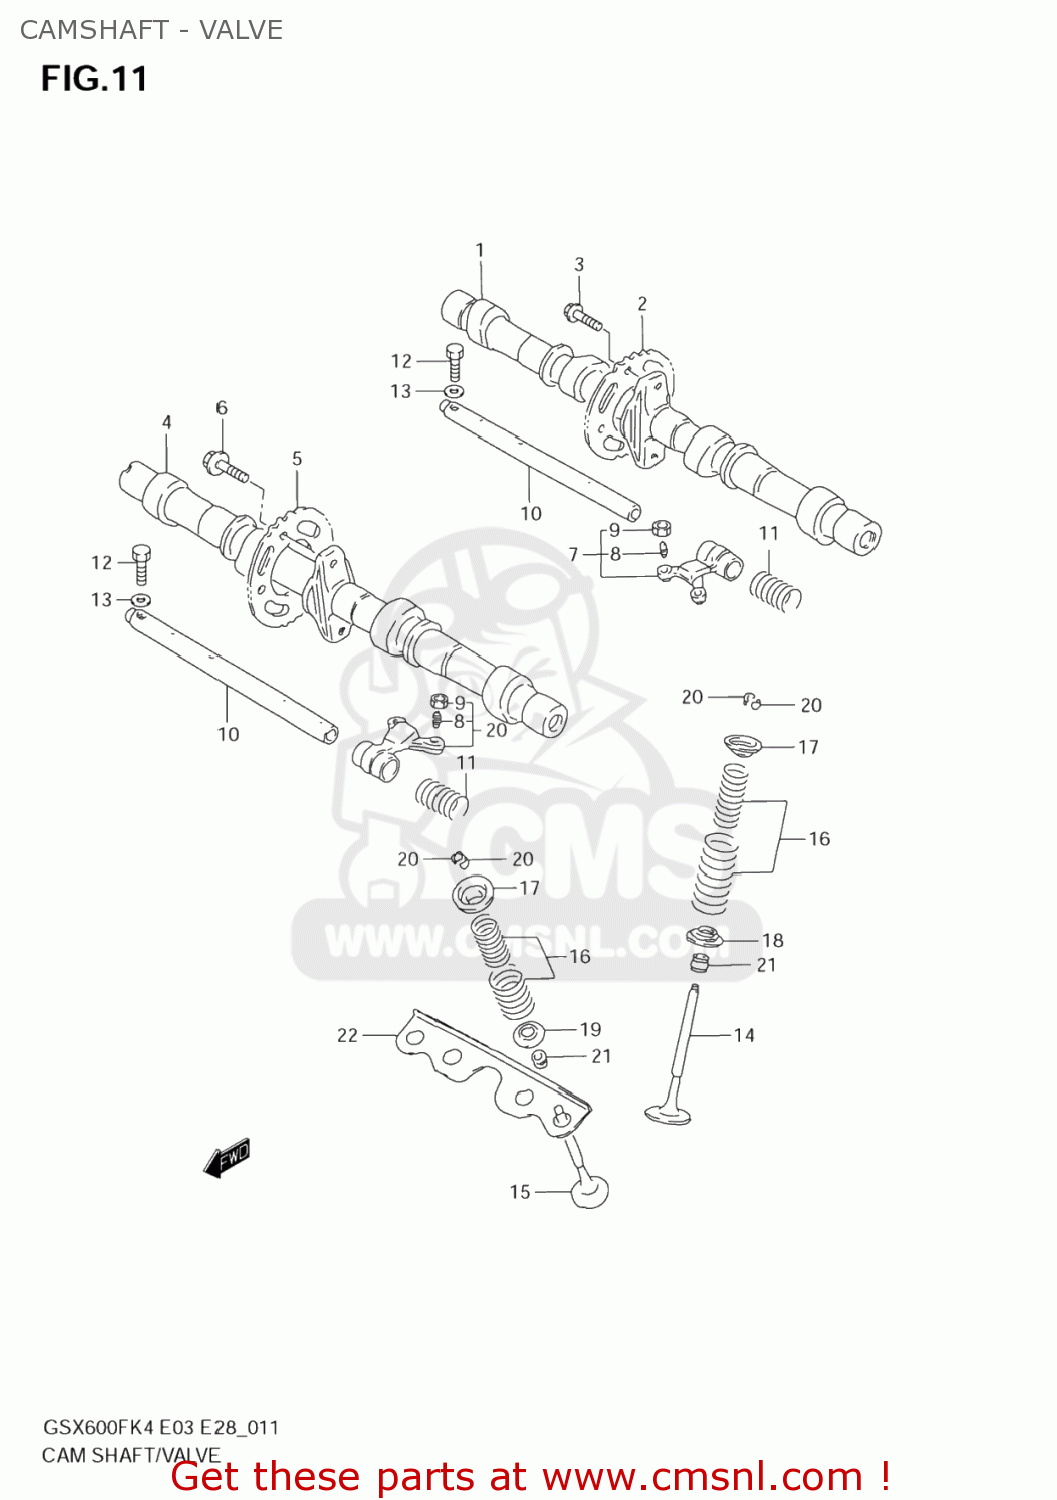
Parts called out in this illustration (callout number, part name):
1	CAMSHAFT,INTAKE
2	SPROCKET,CAMSHAFT
3	BOLT(7X11)
4	CAMSHAFT,EXHAUST
5	SPROCKET,CAMSHAFT
6	BOLT(7X11)
7	ARM,VALVE ROCKER
8	SCREW,TAPPET ADJUSTING
9	NUT,TAPPET ADJUSTING
10	SHAFT,VALVE ROCKER ARM
11	SPRING
12	BOLT(6X30)
13	WASHER
14	VALVE,INTAKE
15	VALVE,EXHAUST
16	SPRING SET,VALVE
17	RETAINER,VALVE SPRING
18	SEAT,VALVE SPRING
19	SEAT,VALVE SPRING EXH INNER
20	COTTER VALVE
21	SEAL,OIL(5X10X9.7)
22	PLATE,VALVE SEAT
